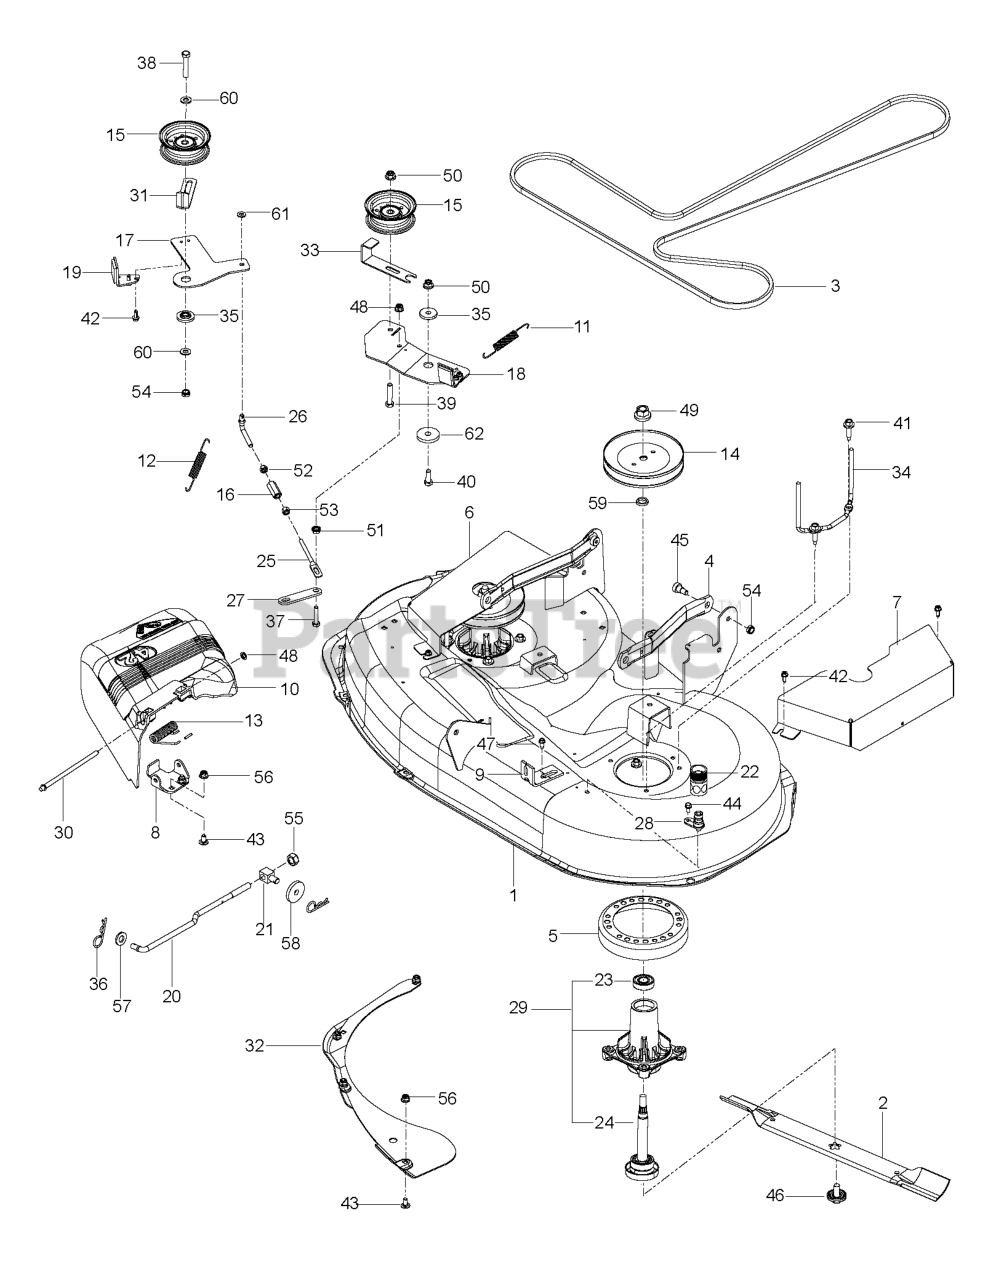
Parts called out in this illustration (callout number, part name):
1	DECK.SVC W/DECALS 42" HTC RZ
2	BLADE.42".MULCH
3	BELT.42.SZ.117.3
4	ARM.SUSPENSION.MOWER
5	STRIPPER-ROUND-UNIVERSAL
6	GUARD.RIGHT.BELT.42"BLACK
7	GUARD.LEFT.BELT.42" BLACK
8	BRKT.DEFLECTOR.38"2005+
9	BRACKET.CLUTCH.CABLE
10	DEFLECTOR 42
11	SPRING RETURN
12	SPRING BRAKE RETURN 42 SZ
13	SPRING, TORSION DEFLECTOR
14	PULLEY.MANDREL.5.438.P
15	IDLER PULLEY
16	ROD END COUPLER
17	ARM.BRAKE.42.BLACK
18	ARM.IDLER.BLACK
19	ARM, LH BRAKE
20	LINK LIFT SUSP. FRONT MOWER
22	COUPLING.QUICK CONNECT
24	SHAFT.ASM.MDRL.N/GREASE.38
26	LINK SZ42 ADJ, PINNED END
27	PLATE.ATTACHMENT.CLUTCH.(2 2)
28	PORT.WASHOUT
29	MANDREL.ASM.SUB-NON.GR
30	ROD, HINGE
31	GUIDE, BELT
32	BAFFLE VORTEX 42
33	KEEPER, BELT
34	BELT KEEPER.MANDREL.38"COATED
35	SPACER.RETAINER
36	HAIRPIN #4
37	CAPSCREW 5/16 X 1/1/2 HEX HEAD
38	HCS 3/8C X 2
39	HCS 3/8-16 X 1 3/4 GR5
40	HCS 3/8-16X1.GRD.5.ZD
41	WASHER HEAD SCREW
42	SCREW- 1/4-20 X 5/8
43	CARRIAGE BOLT 5/16C X 5/8"
44	SCREW 3/8C X 3/4 HEX CAP
45	SB 3/8-16 X 3/8 SKT HD ZD
46	BOLT.WASHER.ASM.7/16-2
47	BOLT.5/16HEX.WHS.HD
48	NUT PUSH M
49	LOCKNUT - 9/16
50	NUT 3/8-16 HEX FLG NYLOC ZD
51	NUT 5/16C WHIZ
52	NUT 5/16F LEFTHAND
54	NUT HEX 3/8-16 NYLON, THIN
55	NUT, 7/16-20 HEX NYLOC ZC
56	5/16-18 NYLOC FLANGE NUT
57	WASHER 1/2" FLAT
58	SPINDLE WASHER
59	WASHER.SPACER.MANDREL
60	WASHER 3/8 SAE FLAT
61	FLAT WASHER 5/16 SAE
62	WASHER, FRICTION
